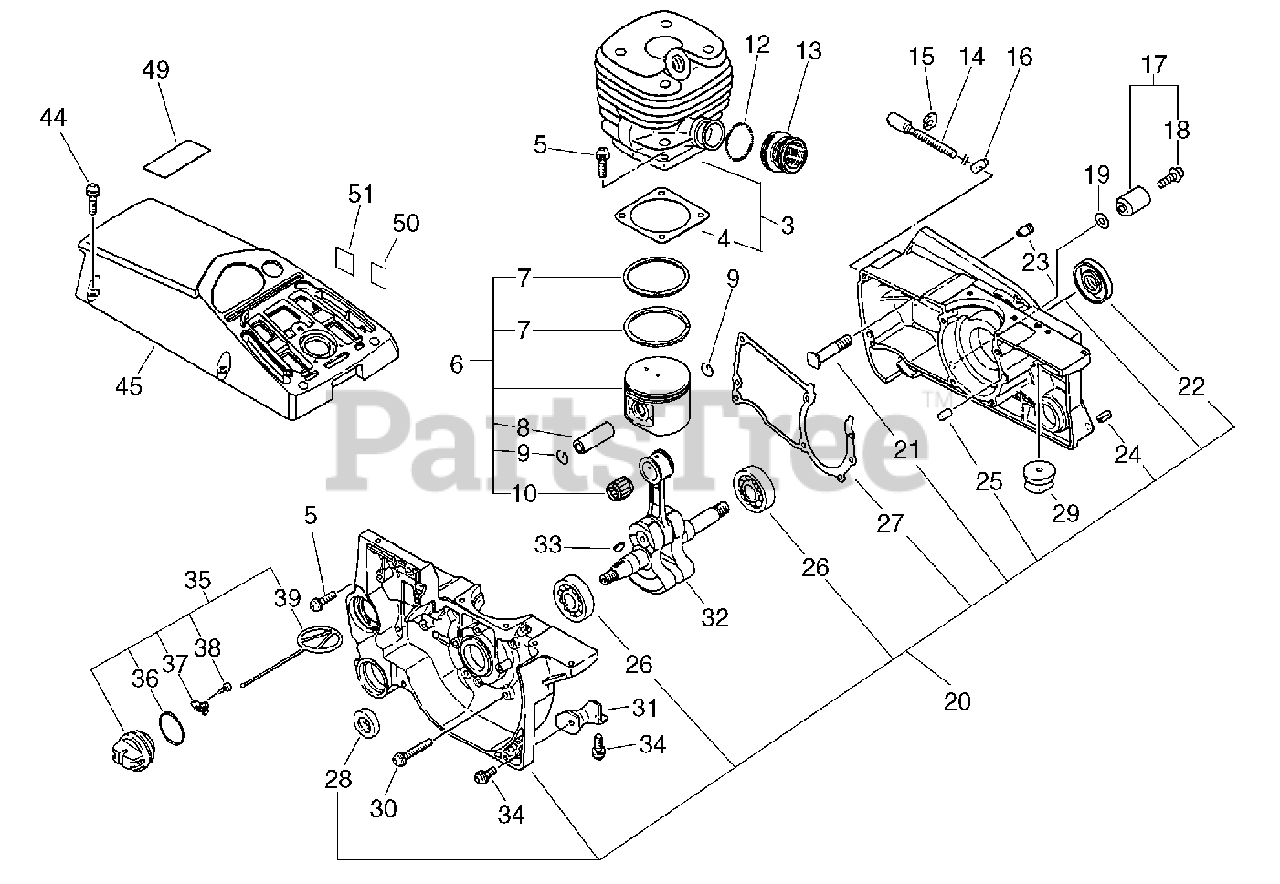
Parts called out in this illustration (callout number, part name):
3	CYLINDER
4	GASKET, CYLINDER
5	SCREW - 5X20
6	PISTON KIT
7	RING, PISTON
8	PIN, PISTON
9	RING, RETAINING
10	BEARING, NEEDLE
13	BELLOWS, INTAKE
14	SCREW, TENSIONER
16	TENSIONER, CHAIN
17	CHAIN CATCHER KIT
18	SCREW - 5X18
19	WASHER - 5
20	CRANKCASE KIT
21	STUD, GUIDE BAR
22	SEAL, OIL
23	VENT, TANK
24	PIN - SPRING -- 5X10
25	PIN - LOCATING
26	BEARING, BALL - 6202
27	GASKET, CRANKCASE
28	SEAL, OIL
30	SCREW - 5X35
32	CRANKSHAFT ASSY
34	SCREW - 5X14
35	CAP ASSY
36	O-RING - 25
37	RETAINER
38	SCREW - 3X8
39	CONNECTOR, CAP
44	SCREW - 5X20
45	COVER, ENGINE
49	LABEL - CAUTION
50	LABEL - CAUTION
51	LABEL - ADJUSTING
